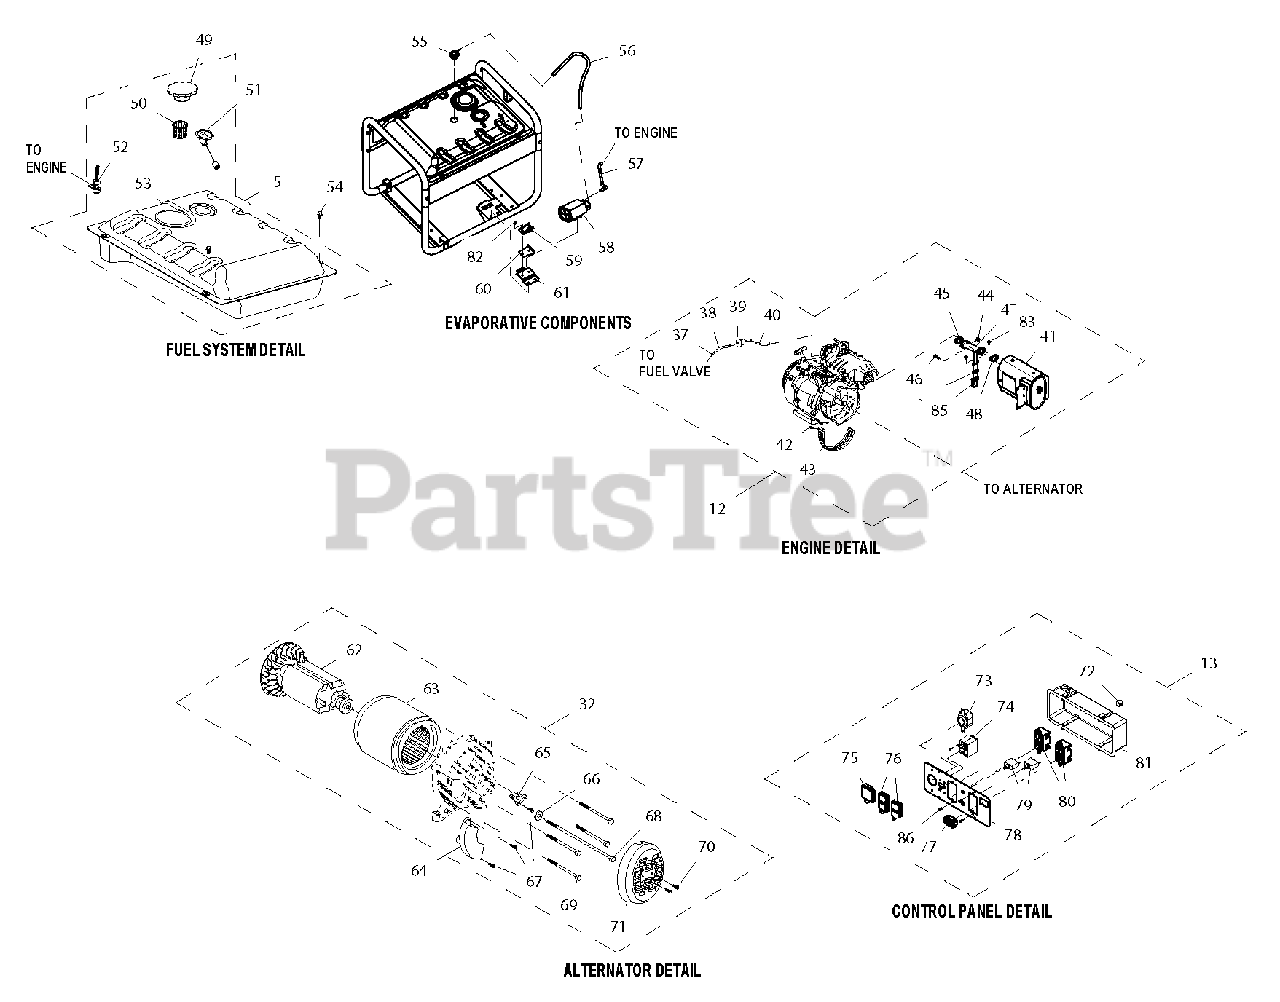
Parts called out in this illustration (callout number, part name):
37	CLAMP HOSE BAND SPRING .38
38	FUEL HOSE 4 ID X 8.5OD X 55MM
39	FUEL FILTER 389
40	FUEL HOSE 4 ID X 8.5OD X 80MM
41	ASSY MUFFLER GP CARB
42	SCREW HHC M5-0.8 X 10 C8.8
43	ALTERNATOR SCROLL GP
44	NUT HEX M8-1.25 G8 CLEAR ZINC
45	GASKET EXHAUST 389CC
46	SCREW HHFC M8-1.25 X 25 W/M10
47	MANIFOLD 389 CARB FOR AIR VLV
48	GASKET EXHAUST, 389CC MFLR SIDE
49	ASSY GAS CAP SEALED - CHROME
50	FILTER, FUEL
51	FUEL GAUGE 130LG
52	VALVE FUEL SHUTOFF
53	FUEL TANK WLDMNT GP 7 GAL CARB
54	SCREW HHFC M8-1.25 X 20 W/M10
55	ASSEMBLY ROV
56	HOSE FORMED ROV-C. CANISTER
57	BREATHER TUBE CARBON CANISTER
58	CARBON CANISTER
59	BRKT CARBON CANISTER MNT
60	BRKT CARBON CANISTER STOP
61	BRKT FRAME TO CARBON CANISTER
62	ASSY ROTOR W/FAN VN
63	ASSY STATOR VN CARB
64	AVR
65	ASSEMBLY,BRUSH VN
66	WASHER FLAT M10
67	SCREW HHFC M5-0.8 X 16
68	SCREW HHC M10-1.5 ROTOR
69	SCREW HHC M6-1.0 STATOR
70	SCREW HHFC M5-0.8 X 12
71	COVER ALTERNATOR INLET 5-7KW
72	SNAP BUSHING .75 OPEN
73	OUTLET 30A 120/250V SPCGR
74	BREAKER 1P 120V CUL/CSA JOEMEX
75	COVER,30A 120/240V
76	COVER, 20A 120V GFCI/DUPLEX
77	HOUR METER W/ALERTS AC/DC
78	FACE PLATE GP PORTABL PS CSA
79	CB 20A 1P 120V CUL/CSA JOEMEX
80	OUTLET 20A 120V GFCI GF20BK
81	RECPTACLE PANEL STORM-GEN
82	SCREW HHFCS M6-1 X 12 G8.8
83	SCREW HHFC M6-1.0 X 8 G8.8
84	GASKET AIR VALVE 2010 CARB
85	AIR VALVE 2010
86	SCREW PPPH #8-16 X .66" BZC
